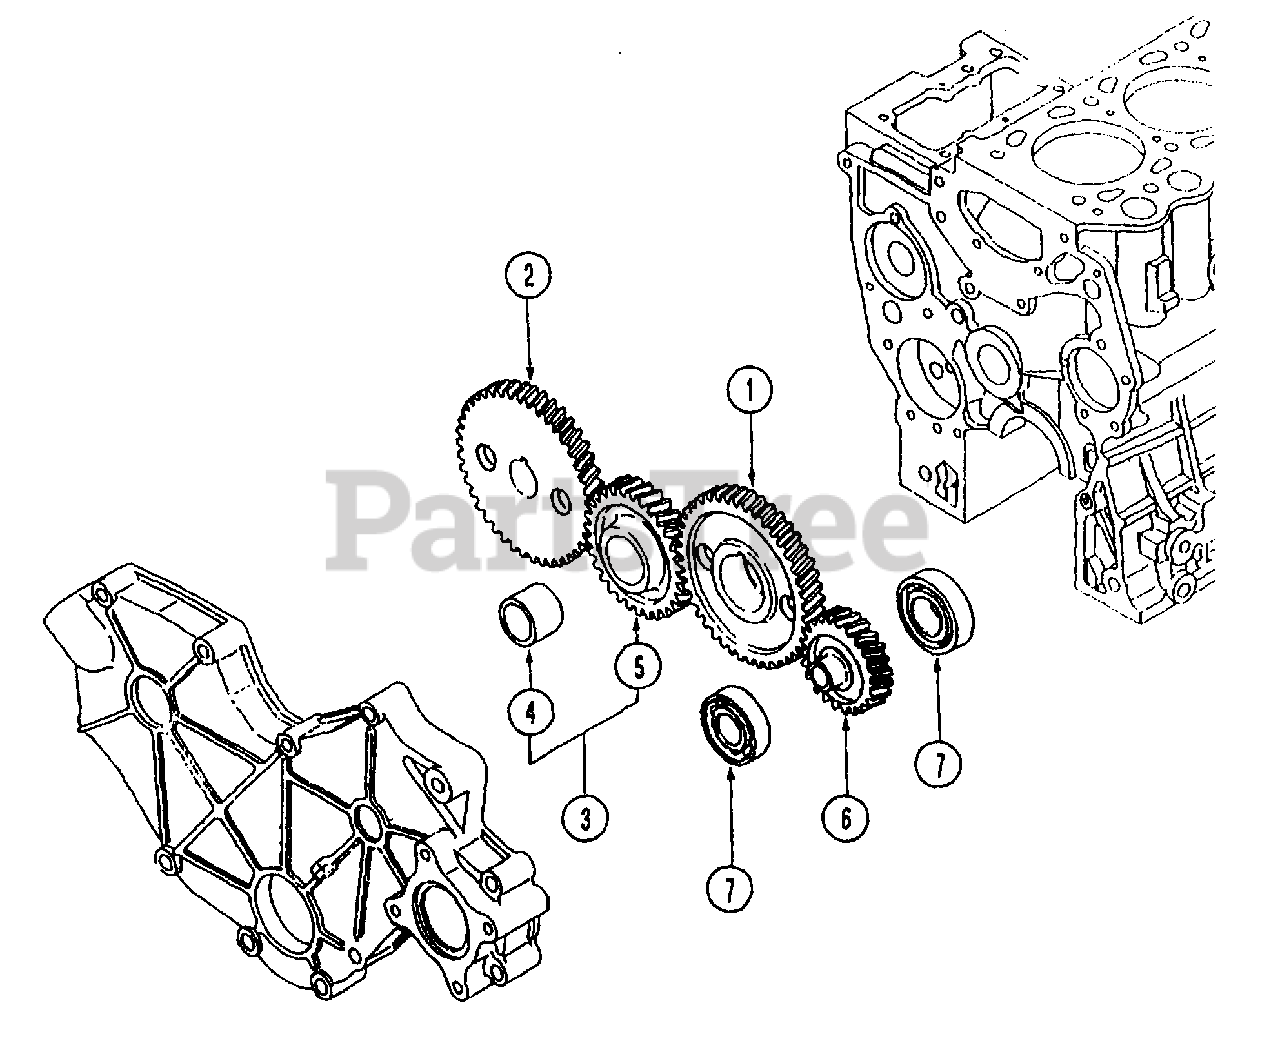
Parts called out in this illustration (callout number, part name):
1	Gear,Camshaft
2	Gear, Inj. Pump
3	Gear Ass'y., Idler
4	Bushing, Idler
5	Gear, Idler
6	Gear, Press.Oil Pump
7	Bearing, Rear
